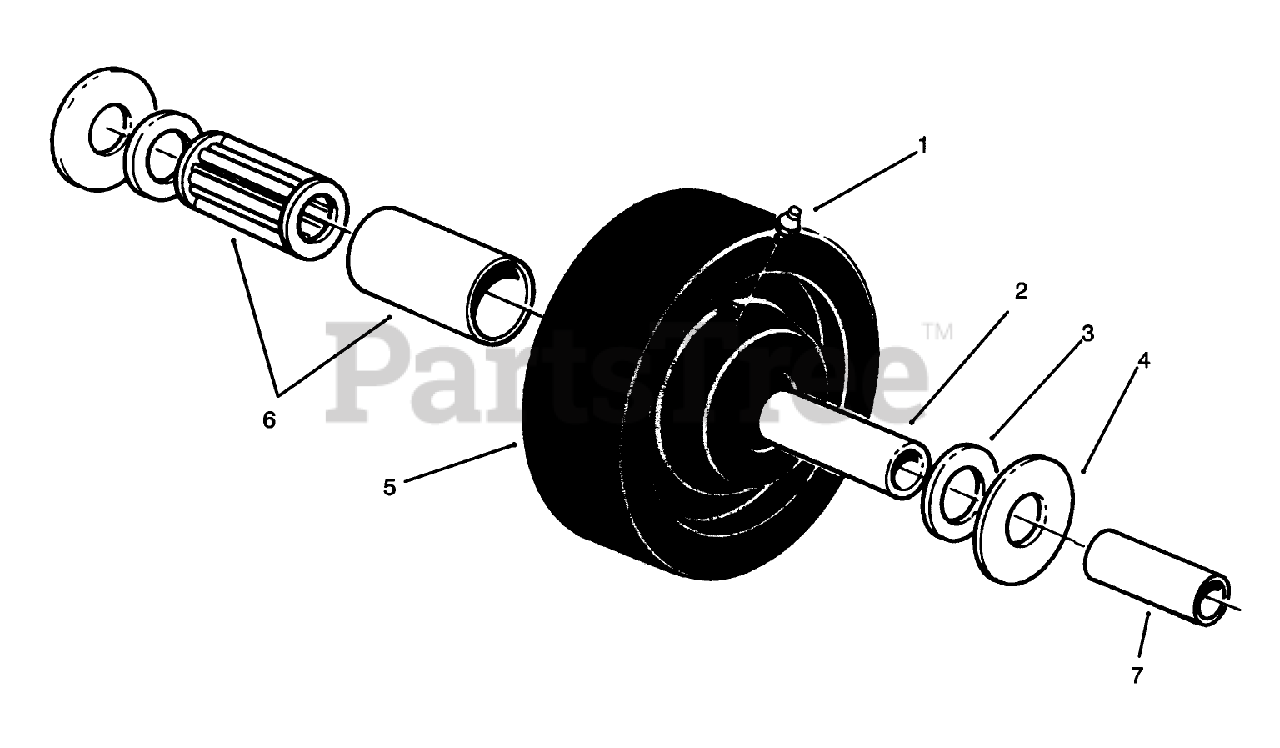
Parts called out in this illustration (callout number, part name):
1	Fitting-Grease
2	SPANNER BUSHING
3	BEARING RETAINER
4	THRUST WASHER
5	WHEEL
6	ROLLER BEARING
7	SPANNER-TIRE
